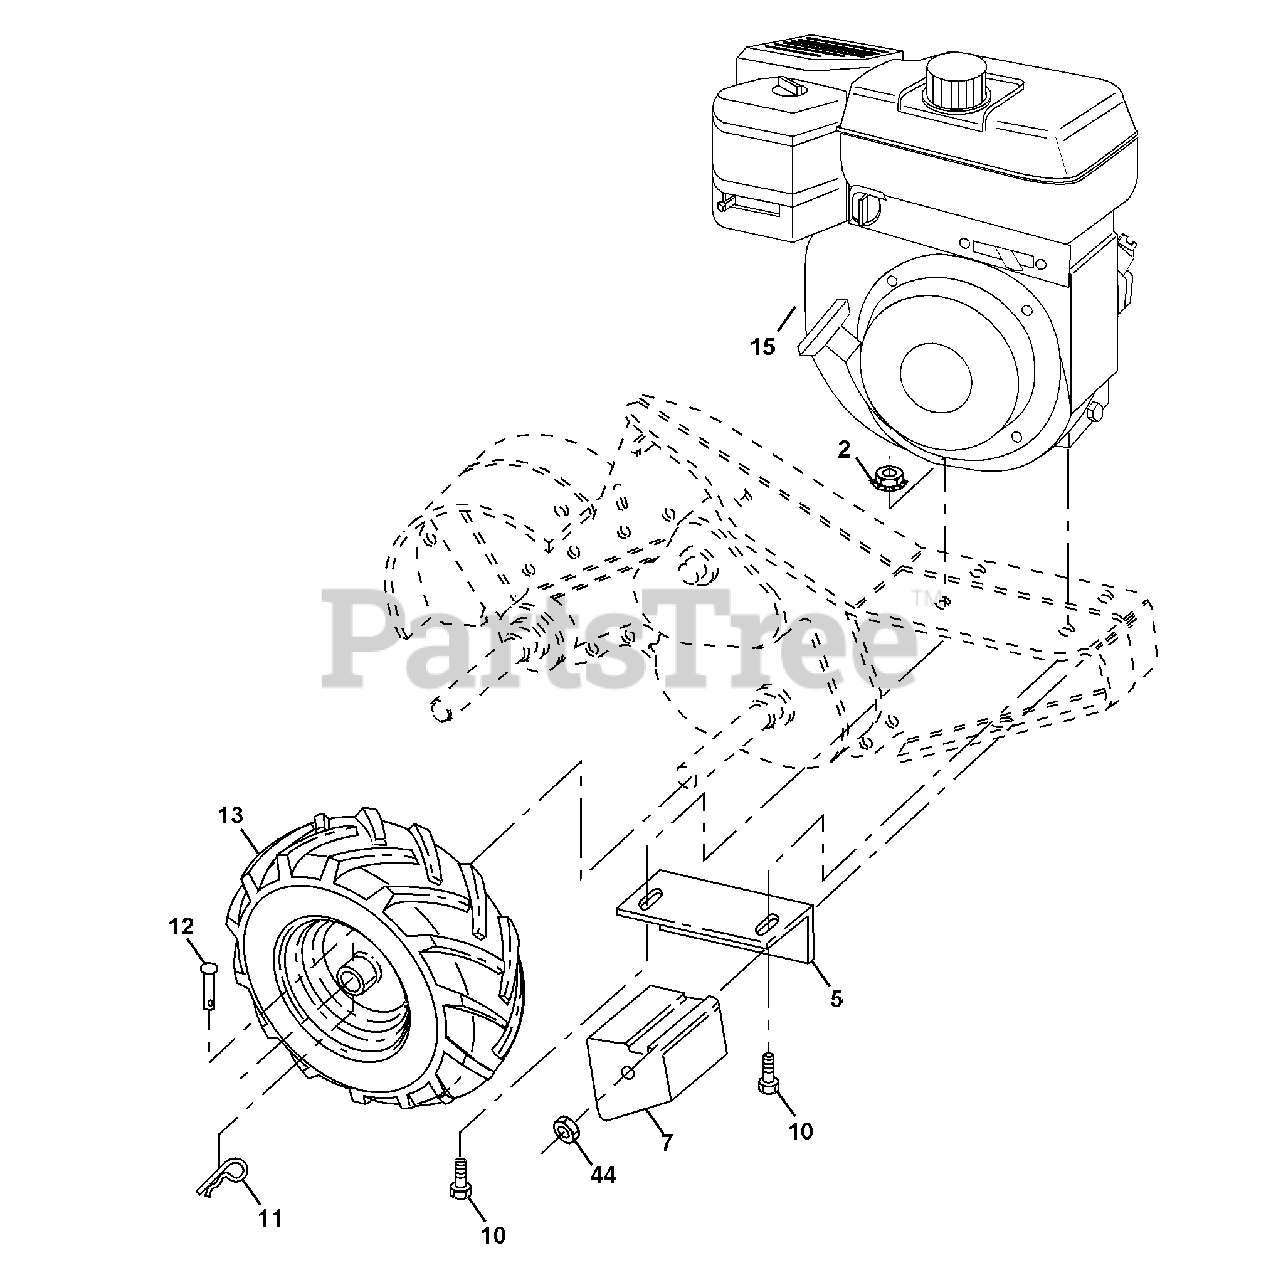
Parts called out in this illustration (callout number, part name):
2	Locknut, Hex, Flange 5/16-18
5	Bracket, Reinforcement RH
7	Counter Weight, R.H.
10	Bolt, Hex 5/16-18 x 1-1/2
11	Clip, Hairpin
12	Rivet, Drilled
15	Engine, Briggs & Stratton
44	Nut, Keps Hex 3/8-16 unc
